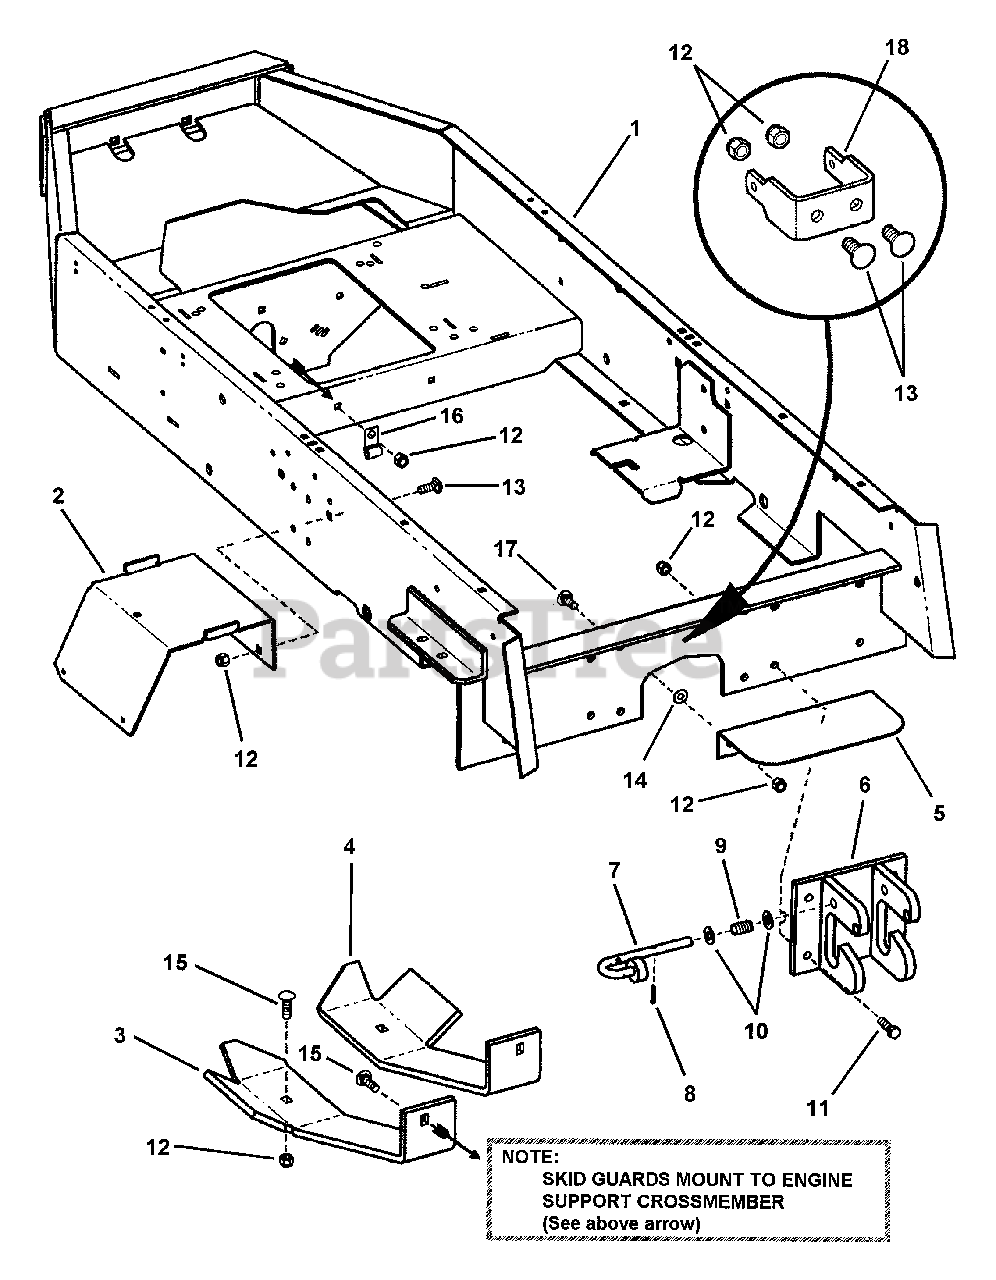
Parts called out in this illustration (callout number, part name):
1	CHASSIS, Lower
2	BRACKET, Battery Support
3	SKID GUARD, R.H.
4	SKID GUARD L.H.
5	SHIELD, Grass
6	PLATE, Hitch
7	PIN, Hitch
8	PIN, Cotter, 1/8 x 3/4"
9	SPRING
10	WASHER, 15/32 I.D. x 15/16" O.D., Flat
11	BOLT, 3/8-16 X 1-1/4" GD5 CZ
12	NUT, 3/8-16 HEX NYLON LOCK
13	BOLT, 3/8-16 x 1" Carriage, Grade 5
14	RETAINER, 3/8" Bolt
15	BOLT, 3/8-16 x 1-1/4", Carriage, Grade 5
16	J-CLIP, Open Cushioned
17	BOLT, 3/8-16 x 1-1/4" Short Neck Carriage, Grade 5
18	BRACKET, Cylinder
